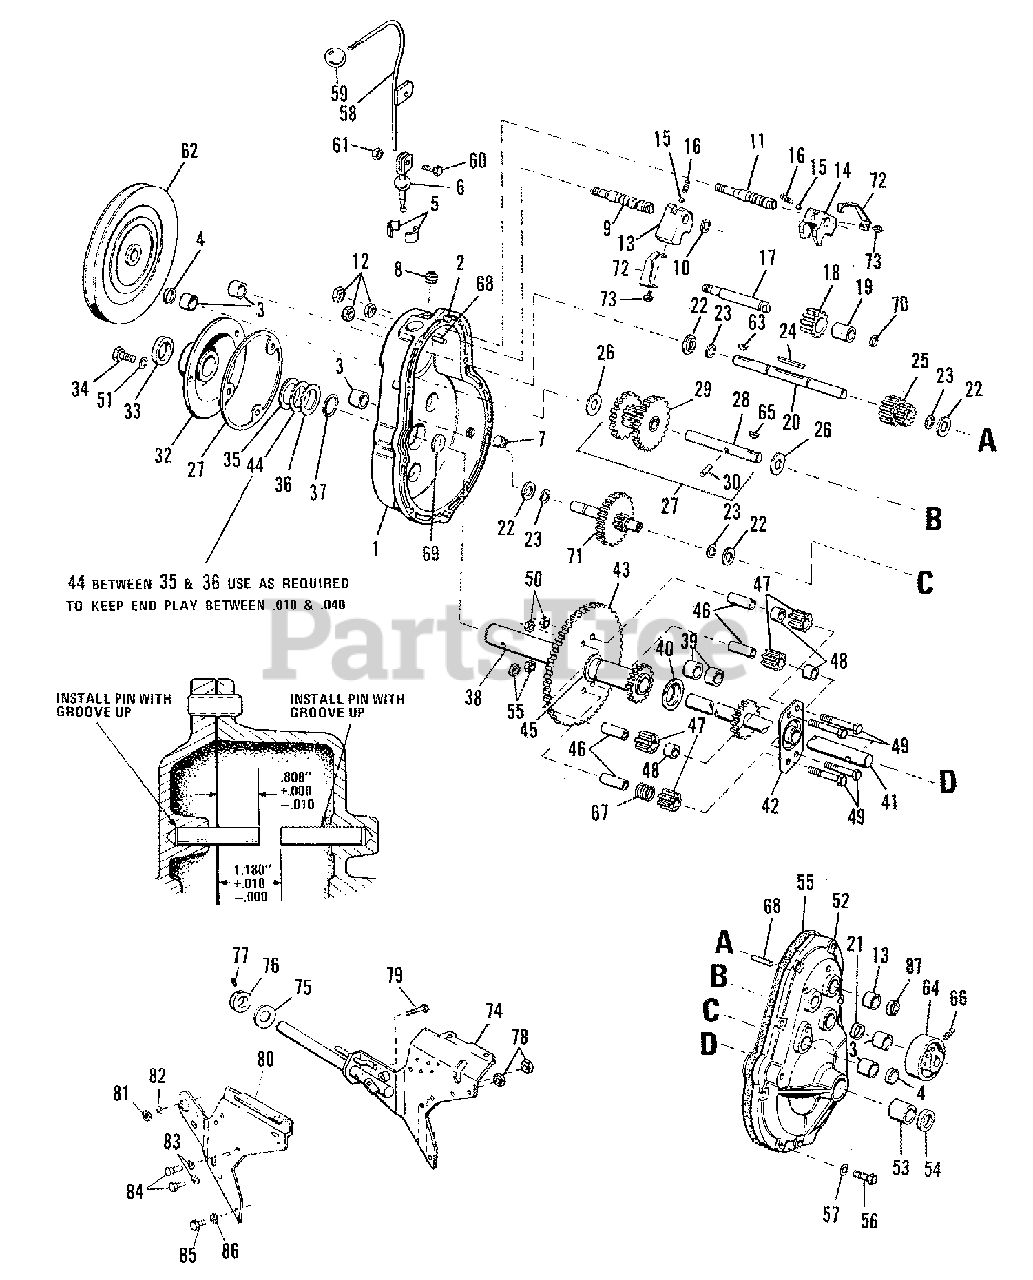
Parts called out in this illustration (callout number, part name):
1	GEAR CASE, (Sub- Assembly Includes 1,2,3,4,5,6,& 68)
2	PIN, Roll, 3/8" Diameter x 1"
5	BUSHING, Half Ball
6	SHIFT ROD ASSEMBLY
7	PLUG, Pipe, 3/8"
9	SHAFT, Shift, Reverse & 1st
10	RING, Retainer
11	SHAFT, Hi-Lo Shift
12	NUT, Full, Hex 7/16"-14
13	FORK, Reverse Shift
14	FORK, I & II Shift
15	BALL, Shift Lock
17	SHAFT, Reverse Pinion
18	PINION, Reverse
19	BEARING, Roller
20	SHAFT, Pulley
23	RING, Retainer
25	HI & LO PINION ASSEMBLY
27	SHAFT & GEAR ASSEMBLY
28	SHAFT, Brake
29	CLUSTER GEAR ASSEMBLY
30	PIN, Dowel
32	PLATE SUPPORT ASSEMBLY
33	SEAL, Oil
34	CAPSCREW, Hex, 3/8"-16 x 7/8"
37	RING, Snap
38	AXLE & BUSHING ASSEMBLY R.H.
40	CAP, Thrust
41	LEFT HAND AXLE ASSEMBLY
42	DIFFERENTIAL PLATE ASSEMBLY
43	GEAR, Drive
46	SPINDLE, Differential, Pinion
47	PINION, Differential
48	SPACER, Differential
49	CAPSCREW, Hex, 3/8"-16 x 2-1/2"
50	LOCKNUT, Full Hex, 3/8"-16
51	LOCKWASHER, 3/8"
52	COVER, Gear Case (Sub Assembly, Includes 3,4,53,68)
55	GASKET, Case
56	CAPSCREW, Hex, 5/16"-18 x 1-1/4"
57	LOCKWASHER, 5/16"
58	SHIFT LEVER ASSEMBLY
60	CAPSCREW, Hex, 1/4-20 x 3/4"
61	LOCKNUT, Full Hex 1/4-20
62	PULLEY, Transmission
64	DRUM, Brake
66	SETSCREW, 5/16"-18 x 1/2"
68	PIN ROLL ASSEMBLY
69	PLUG, Expansion
71	GEAR & SHAFT ASSEMBLY
73	SCREW, Cap, Hex, 5/16" 18 X 5/16" Large
74	PLATE, R.H.
76	COLLAR, Set
77	SCREW, Set, Square Head, 5/16 18 x 1/2"
78	NUT, Full, Hex, 7/16"-14
79	CAPSCREW, Hex, 3/8"-16 x 3/4
80	PLATE, L.H.
81	NUT, Full Hex, 3/8-16
82	LOCKWASHER, 3/8"
83	LOCKWASHER, 7/16
84	CAPSCREW, Hex, 7/16-14 x 1
85	CAPSCREW, Hex, 3/8-16 x 3/4
86	LOCKWASHER, 3/8"
87	PLUG, Expansion
